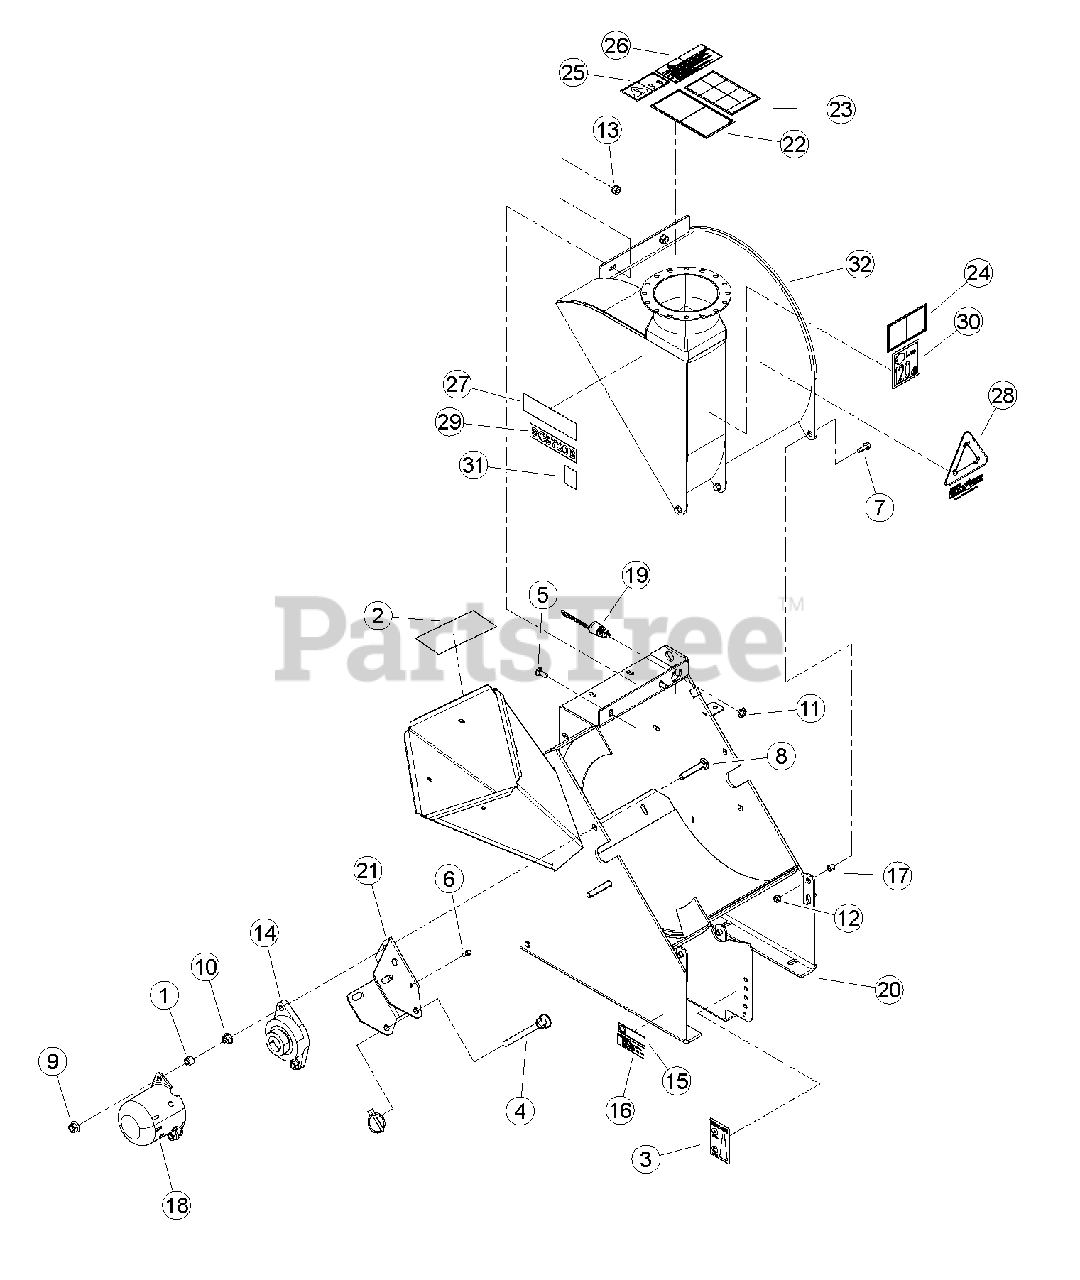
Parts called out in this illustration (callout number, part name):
1	BUSHING, 1/2 ID X 3/4 OD X 17/32 LNST
2	DECAL, BLADE DANGER ISO
3	DECAL, SHRED SIZE
4	PIN, HITCH 1/2 X 6-1/2 W/ LYNCH
5	BOLT, 3/8 X 1" CRG GR5 NC ZP
6	BOLT, 1/4-20 X 3/4 HWH GR5 CZP
7	BOLT, 5/16 X 1 FLANGE NC
8	BOLT, 1/2 X 3.00 GR5 ZP CRG
9	NUT, 1/2-13 NYLOCK FLANGE
10	NUT, 1/2 SPIRAL LOCK NC ZP
11	NUT, 5/8-32 JAM
12	NUT, 5/16-18 NYLOCK-FLANGE
13	NUT, 3/8-16 NYLOCK-FLANGE
14	BEARING,2 BLT FLG 1-1/2" BORE
15	DECAL, SC5720B INFORMATION (CE COMPLIANT ONLY)
16	DECAL, ATLANTIC BRIDGE LTD INFO (CE COMPLIANT ONLY)
17	SPACER, .50 X .50
18	CAP, LARGE SHAFT
19	ASSEMBLY, SEALED SWITCH
20	WELDMENT, C/S BOTTOM
21	PLATE, ROTOR LOCK
22	DECAL, KNIFE ACCESS ISO
23	DECAL, OPERATING INSTRUCTIONS ISO
24	DECAL, DISCHARGE ISO
25	DECAL, MAINTENANCE ISO
26	DECAL, MUTILINGUAL MANUAL
27	DECAL, ECHO BEARCAT 6.82 X 1.90
28	DECAL, SHRED IT
29	DECAL, MODEL SC5720B
30	DECAL, 120 DB
31	DECAL, ECHO BEARCAT QR CODE
32	WELDMENT, CHIPPER TOP
